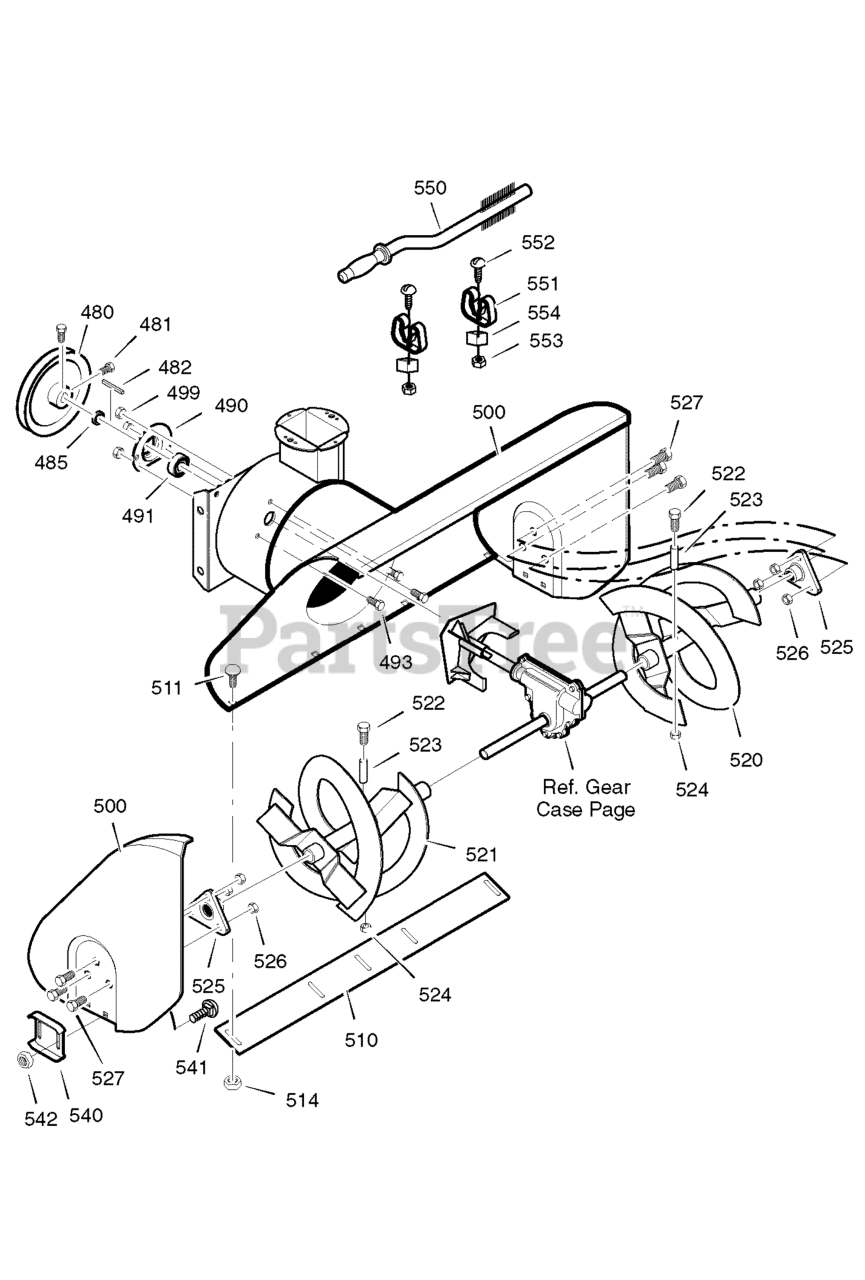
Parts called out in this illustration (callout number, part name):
480	PULLEY, V4L 8.4X .67
481	SCREW, 5/16-18 x 0.63
482	KEY, SQUARE 3/16 X 3/4
485	SPACER, FRICTION PULLEY
490	RETAINER, BALL BRNG
491	BEARING, BALL
493	BOLT, HEX 5/16-18 X 1/2
499	NUT, 5/16-18
500	HOUSING, ASSY
510	BLADE, SCRAPER
511	BOLT, 5/16-18 X 3/4
514	NUT, 5/16-18
520	AUGER, ASSY, LH
521	AUGER, ASSY, RH
522	SCREW
523	SPACER, SLEEVE
524	NUT, 1/4-20
525	BEARING, FLANGE
526	NUT, 5/16-18
527	SCREW, 5/16-18 x 3/4
540	SKID, HEIGHT ADJUST
541	BOLT, 5/16-18 X .75
542	NUT, 5/16-18
550	BRUSH, CLEANOUT
551	CLIP, RETAINER
552	SCREW
554	BLOCK
